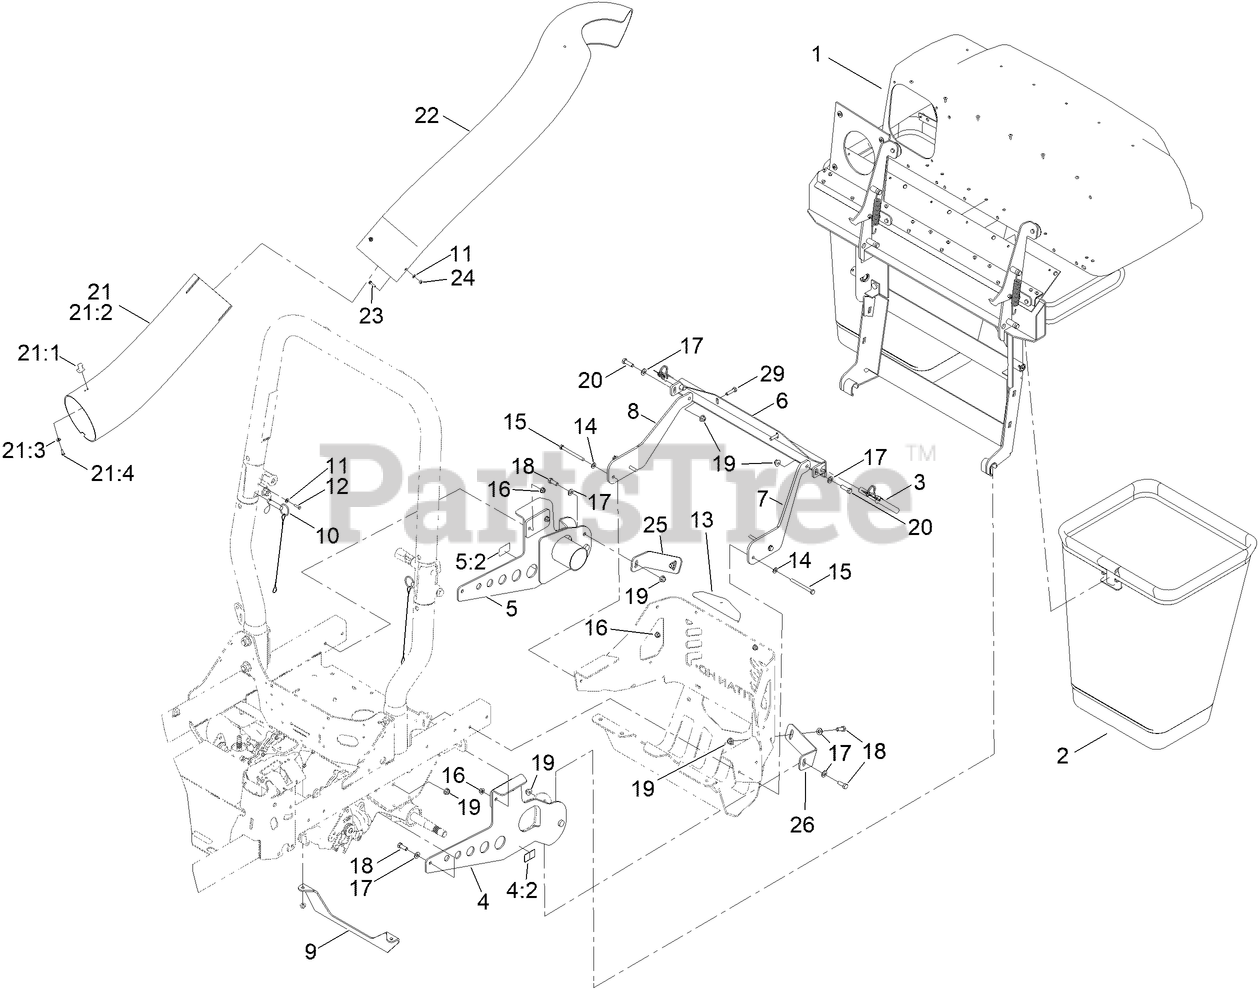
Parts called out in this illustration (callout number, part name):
1	TWIN BAG HOOD ASM
2	BAG AND FRAME ASM
3	PIN-MOUNT, BAGGER
4	SUPPORT-BAGGER, LOWER LH
4:2	DECAL-WARNING
5	SUPPORT-BAGGER, LOWER RH
5:2	DECAL-WARNING
6	SUPPORT-BAGGER, UPPER
7	BRACKET-UPPER, LH
8	BRACKET-UPPER, RH
9	SUPPORT-TRANSMISSION
10	HITCH PIN ASM
11	WASHER-FLAT
12	SCREW
13	COVER-HITCH
14	WASHER-PLAIN
16	NUT-HF, NI
17	WASHER-FLAT
18	SCREW-HH
19	NUT-HF, NI
20	SCREW-HH
21	LOWER TUBE ASM
21:1	TUBE-LOWER, SHORT
21:2	LATCH-KEEPER
21:3	SCREW-PPH
21:4	WASHER-FLAT
22	TUBE-UPPER
23	SCREW-HWH
24	NUT-LOCK, NI
25	BRACKET-BAGGER, RH
26	BRACKET-BAGGER, LH
29	SCREW-HH
